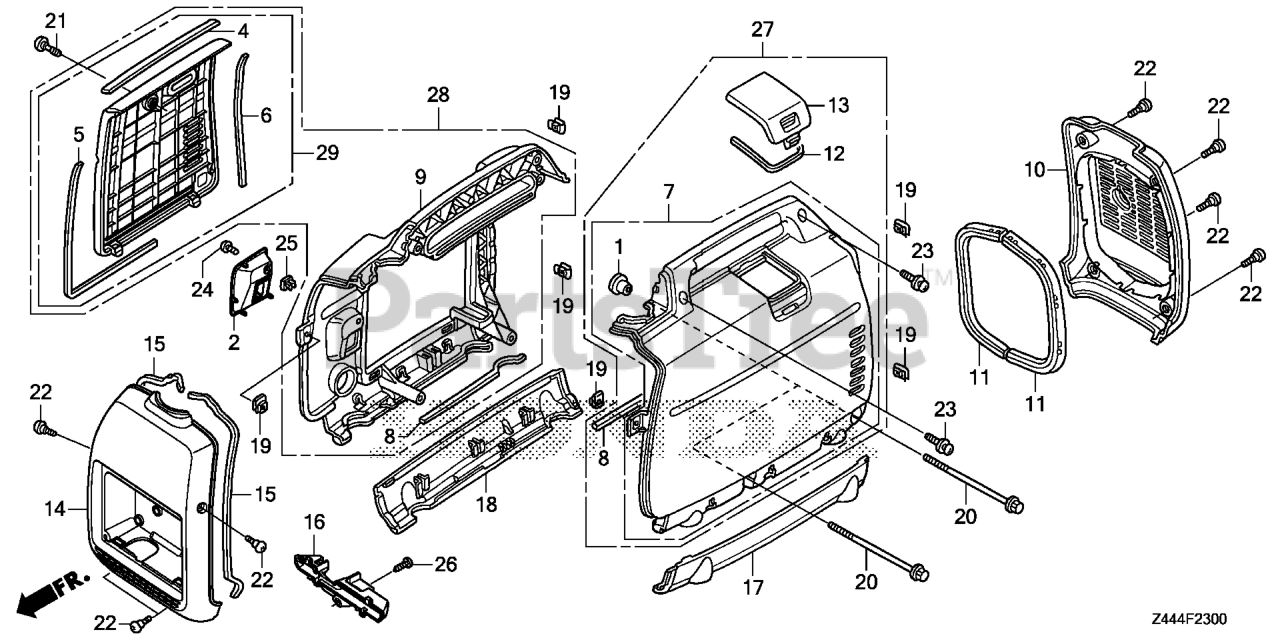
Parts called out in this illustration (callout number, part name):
1	COLLAR, FAN COVER (Honda Code 5580527). (N/A: SEE ASSEMBLY)
2	PROTECTOR, STARTER ROPE
4	SEAL A, MAINTENANCE COVER
5	SEAL B, MAINTENANCE COVER
6	SEAL, MAINTENANCE COVER (C)
7	COVER, SIDE *R280* (POWER RED) (L. SIDE)
7	COVER, SIDE *YRA16L* (REAL CAMO BEIGE 2) (L. SIDE)
8	SEAL A, SIDE COVER
9	COVER, L. SIDE *R280* (POWER RED) (R. SIDE)
9	COVER, L. SIDE *YRA16L* (REAL CAMO BEIGE 2) (R. SIDE)
10	COVER, RR. *NH314* (CONDUCT GRAY)
11	RUBBER, RR. COVER SEAL
12	SEAL, PLUG CHECK
13	COVER, PLUG CHECK *R280* (POWER RED)
13	COVER, PLUG CHECK *YRA16L* (REAL CAMO BEIGE 2)
14	COVER, FR. *NH314* (CONDUCT GRAY)
15	SEAL, FR. COVER
17	PLATE, SIDE (LOWER) *NH314* (CONDUCT GRAY) (L. SIDE)
18	PLATE, SIDE (LOWER) *NH314* (CONDUCT GRAY) (R. SIDE)
19	NUT, FENDER SETTING
20	BOLT, FLANGE (6X137)
21	SCREW, SPECIAL (6X16)
22	SCREW, SPECIAL (6X15)
23	SCREW-WASHER (6X20)
24	SCREW, TAPPING (5X16) (PO)
25	GROMMET, SCREW (6MM)
26	SCREW, TAPPING (5X16) (PO)
27	COVER SET, SIDE *YRA16L* (REAL CAMO BEIGE 2) (L. SIDE)
27	COVER SET, SIDE *R280* (POWER RED) (L. SIDE)
28	COVER SET, SIDE *YRA16L* (REAL CAMO BEIGE 2) (R. SIDE)
28	COVER SET, SIDE *R280* (POWER RED) (R. SIDE)
29	COVER ASSY., MAINTENANCE *R280* (POWER RED)
29	COVER ASSY., MAINTENANCE *YRA16L* (REAL CAMO BEIGE 2)
